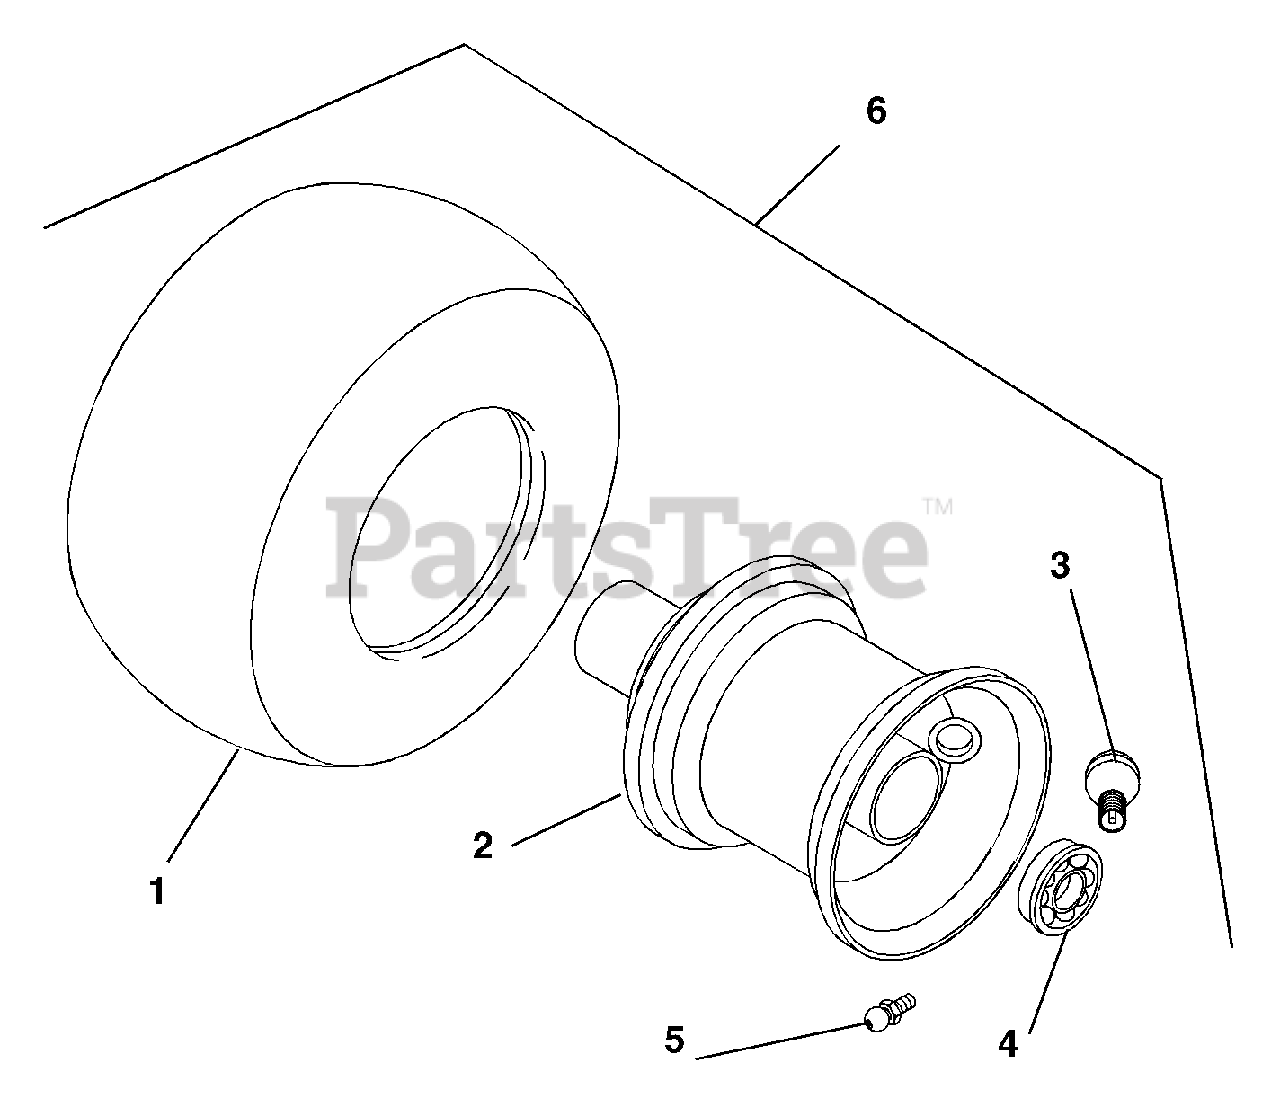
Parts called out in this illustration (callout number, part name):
1	1
2	1
3	1
4	2
5	1
6	2
